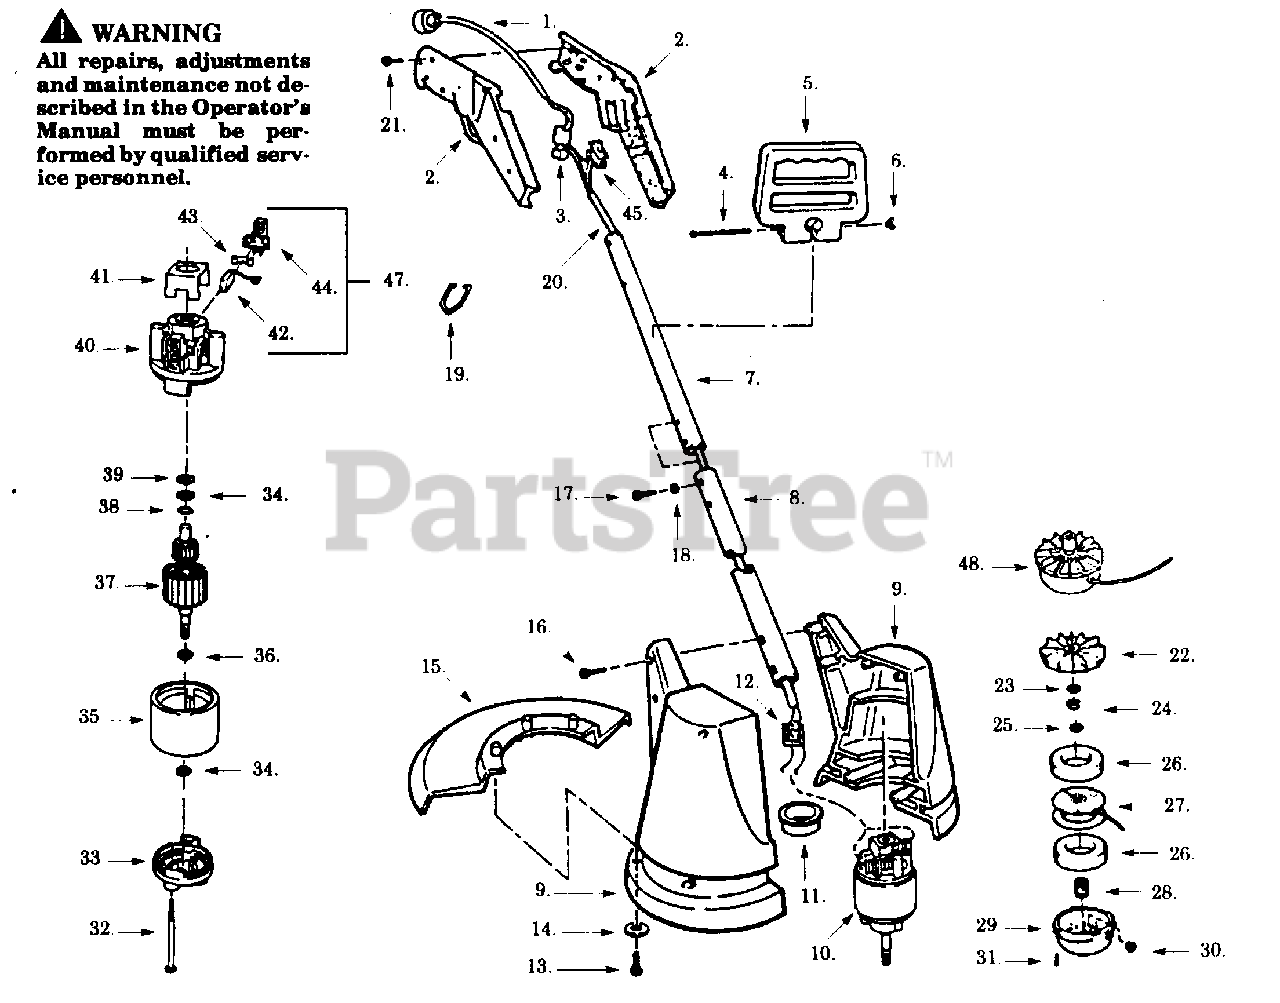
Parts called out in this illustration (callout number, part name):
1	Power Cord
2	R.H./L.H. Handle
3	Trigger Switch
5	Side Handle
6	Wing Nut
7	Upper Tube
8	Lower Tube
9	R.H./L.H. Housing
11	Air Baffle
12	P.C. Bridge Kit
15	Line Cutter Guard
18	Lockwasher
20	Harness Ass'y.
22	Rear Plate
24	Retaining Ring
25	Wire Retaining Ring
26	Foam Pad
27	Spool & Line
29	Hub Ass'y.
31	Cotter Pin
33	Endbell Ass'y. (Drive)
35	Field Ass'y.
36	Retaining Ring
37	Armature Ass'y.
38	Retaining Ring
40	Endbell Ass'y. (Brush)
41	Insulator
43	Brush Spring
44	Brush Holder
45	Power Switch
47	Brush Kit (Incl. 42,43,44)
48	Cutting Head Ass'y.
